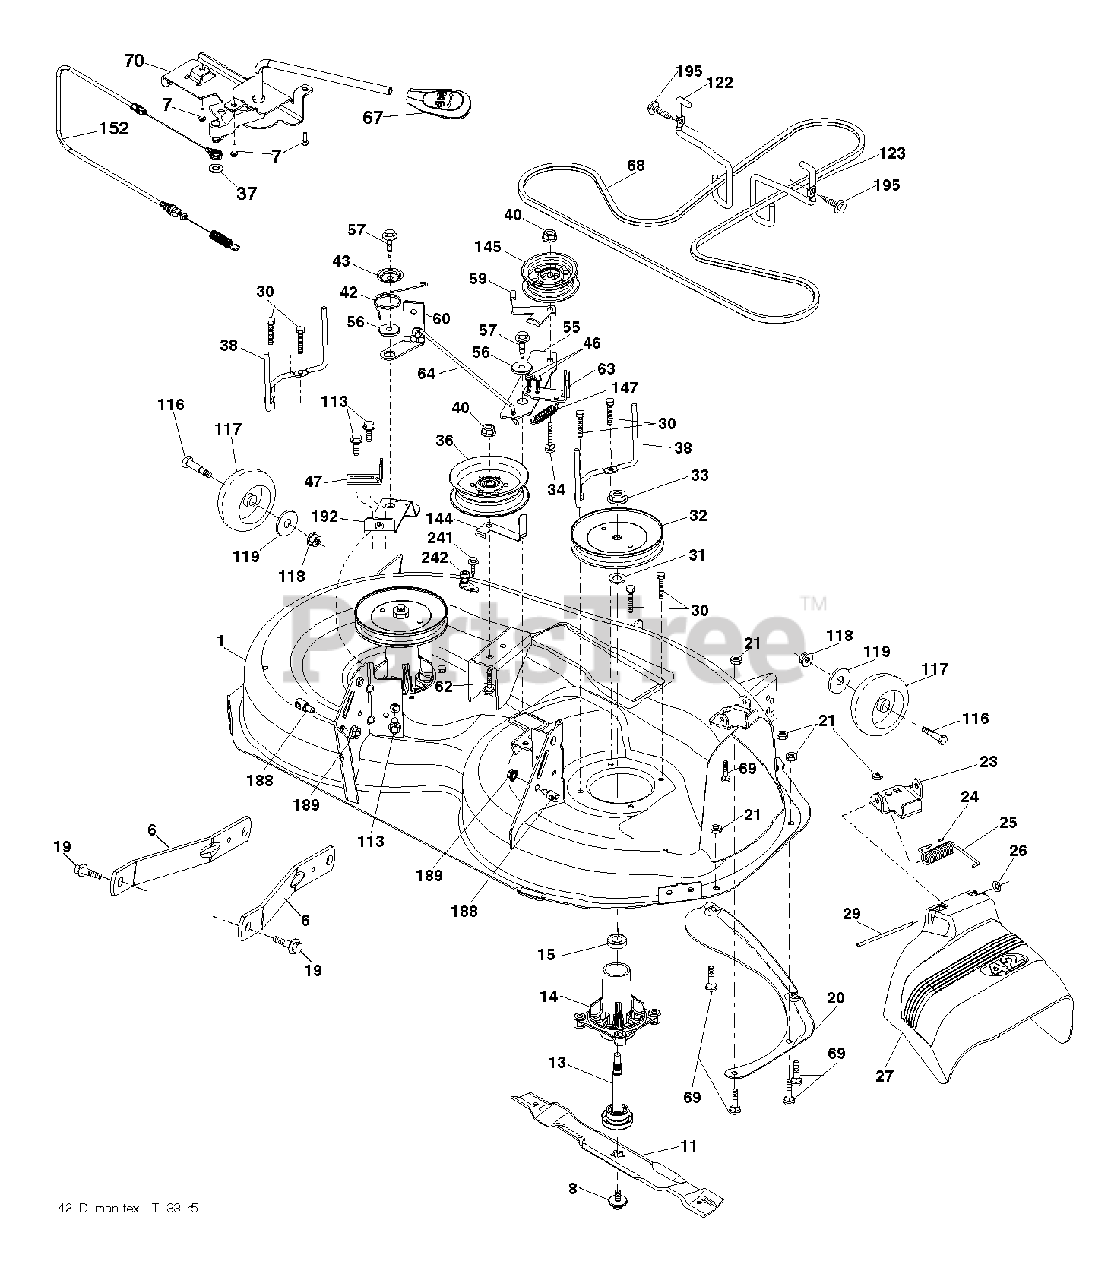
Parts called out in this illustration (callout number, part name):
1	DECK.WELDMENT.42"
6	ARM.SUSPENSION.MOWER.R
7	SCREW.#10 X 0.750.BOS THREAD
8	BOLT.WASHER.ASM.7/16-2
11	42" HI-LIFT BLADE
13	SHAFT.ASM.MDRL.N/GREASE.38
14	HOUSING MANDREL
19	BOLT.SHOULDER
20	BAFFLE.VORTEX
21	LOCKNUT
23	BRKT.DEFLECTOR.38"2005+
24	CAP-SLEEVE LT
25	SPRING.TORSION.DEFLECT
26	NUT PUSH M
27	SHIELD.DEFLECTOR.MOWER.42"BLAC
29	ROD.HINGE
30	SCREW, WASHER HEAD
31	WASHER.SPACER.MANDREL
32	PULLEY.MANDREL.5.438.PD
33	NUT.FLANGE.LOCK.TOP
34	BOLT.3/8-16X1.50
36	PULLEY.IDLER.2006
38	KEEPER.BELT.LH.MANDREL
40	NUT LOCK FLG 3/8-16 UNC
42	SPRING.TORSION.BRAKE
43	SRPING.TORSION.RETAINE
46	SCREW.1/4-20X5/8
47	BRKT.CLUTCH.CABLE
55	IDLER.ARM.42"
56	SPACER.RETAINER
57	SCREW 3/8-16X1
59	GUARD, BELT
60	ARM BRAKE MOWER
62	BOLT
63	ARM BRAKE MOWER
64	LINK BRAKE
67	HANDLE.CLUTCH.CABLE.LT
68	BELT.DRIVE.MOWER.TEX.42"
69	BOLT
70	CLUTCH.ASM.MANUAL.LT.PRED
113	BOLT.5/16HEX.WHS.HD
117	WHEEL.GAGE.HALF.SPOKED
118	NUT LOCK FLG 3/8-16 UNC
119	WASHER
122	KEEPER BELT ENGINE LH
123	KEEPER BELT RH
144	KEEPER.BELT.MOWER
145	PULLEY.IDLER.48"PRIMARY
147	RETURN SPRING
152	CLUTCH CABLE
188	STUD.FASTNER.W/ANTI-ROTATE
189	NUT LOCK HEX FLANGE 5/16-18
192	BRKT.BRAKE.STAND.LH.
195	SCREW, 3/8-16X3/4
242	PORT.WASHOUT
